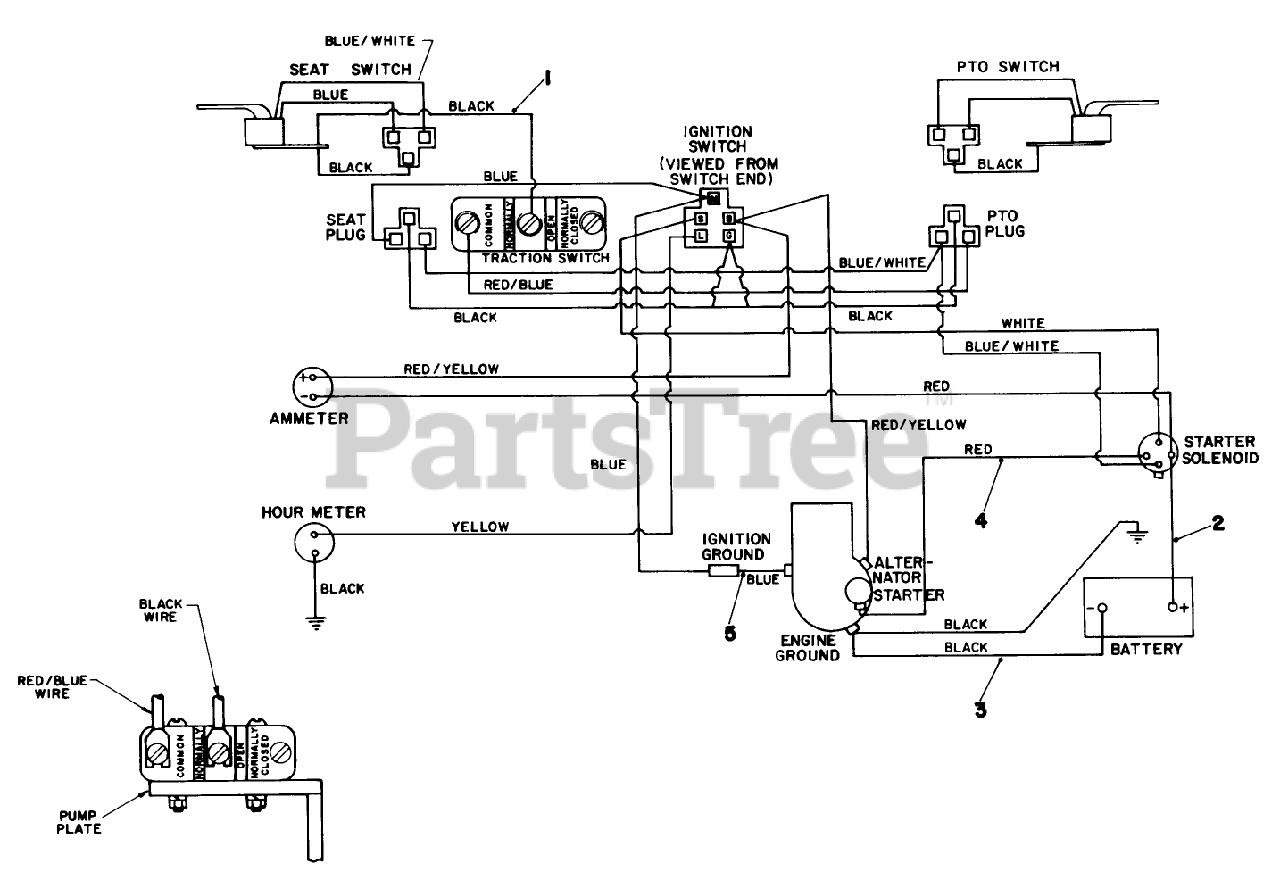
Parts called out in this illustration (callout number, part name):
1	WIRE HARNESS
2	BATT/SOLENOID WIRE
3	BATTERY GROUND WIRE
4	SOLENOID TO START WIR
5	ENGINE GROUND WIRE
